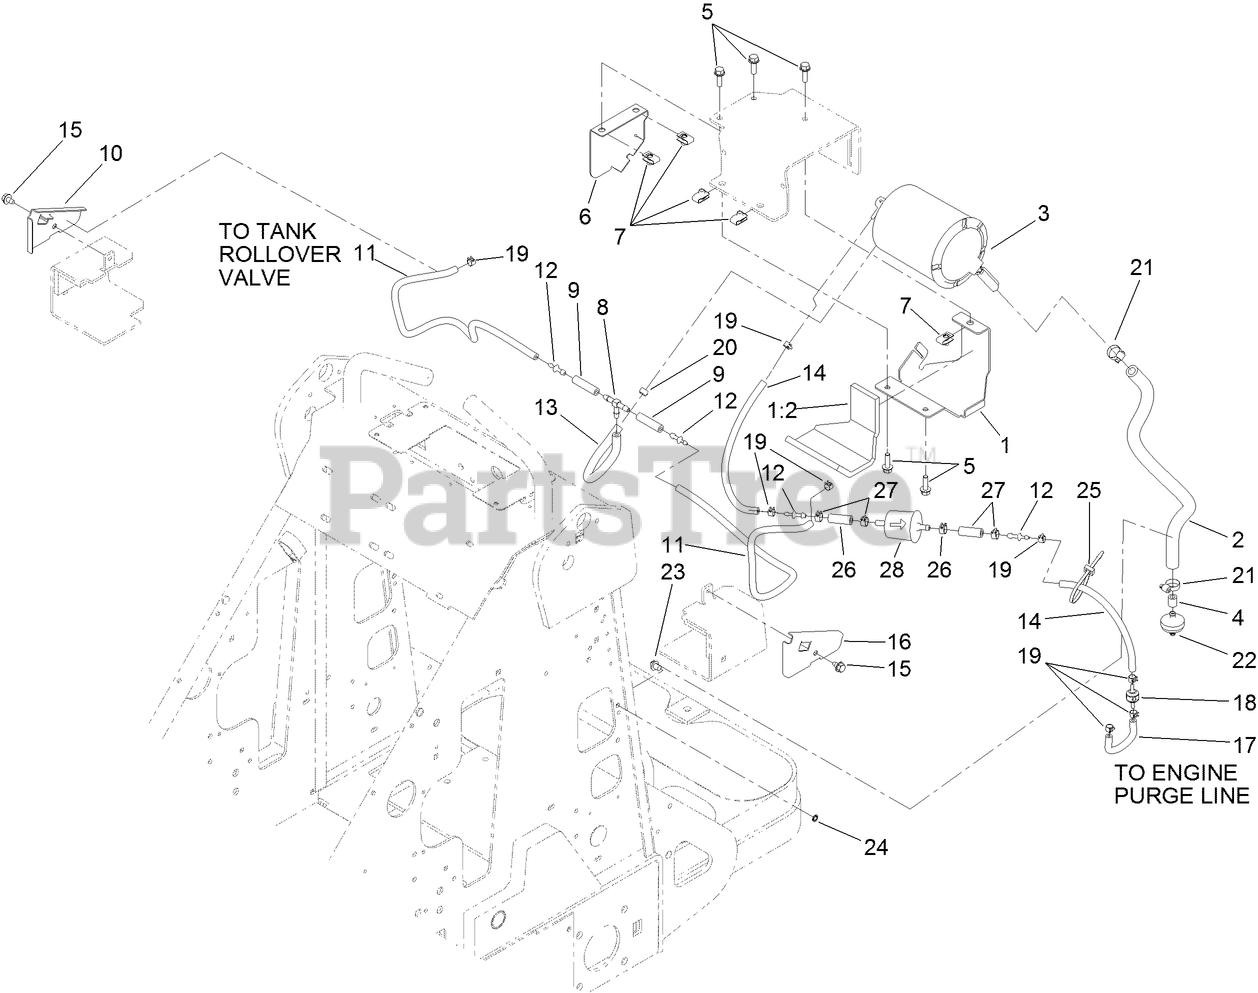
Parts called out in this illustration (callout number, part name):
1	CANISTER MOUNT ASM
1:2	PAD-FOAM
2	HOSE-VENT
3	CANISTER-CARBON, 1200CC
4	HOSE-FUEL
5	SCREW-HHF
6	COVER-CANISTER
7	NUT-CLIP, U
8	FITTING-TEE, BARBED
9	HOSE-FUEL
10	PLATE-HOSE RETAINER, RH
11	HOSE-FUEL
12	FITTING-STRAIGHT
13	Hose-Fuel
14	HOSE-FUEL
15	SCREW
16	PLATE-HOSE RETAINER, LH
17	HOSE-FUEL
18	VALVE-CHECK, VACUUM
19	CLAMP-HOSE
20	CLAMP-HOSE
21	CLAMP-HOSE
22	FILTER-FUEL, INLINE
23	CLIP-TIE
24	WASHER-LOCK
25	TIE-CABLE
26	HOSE-FUEL
27	CLAMP-HOSE
28	FILTER-FUEL
